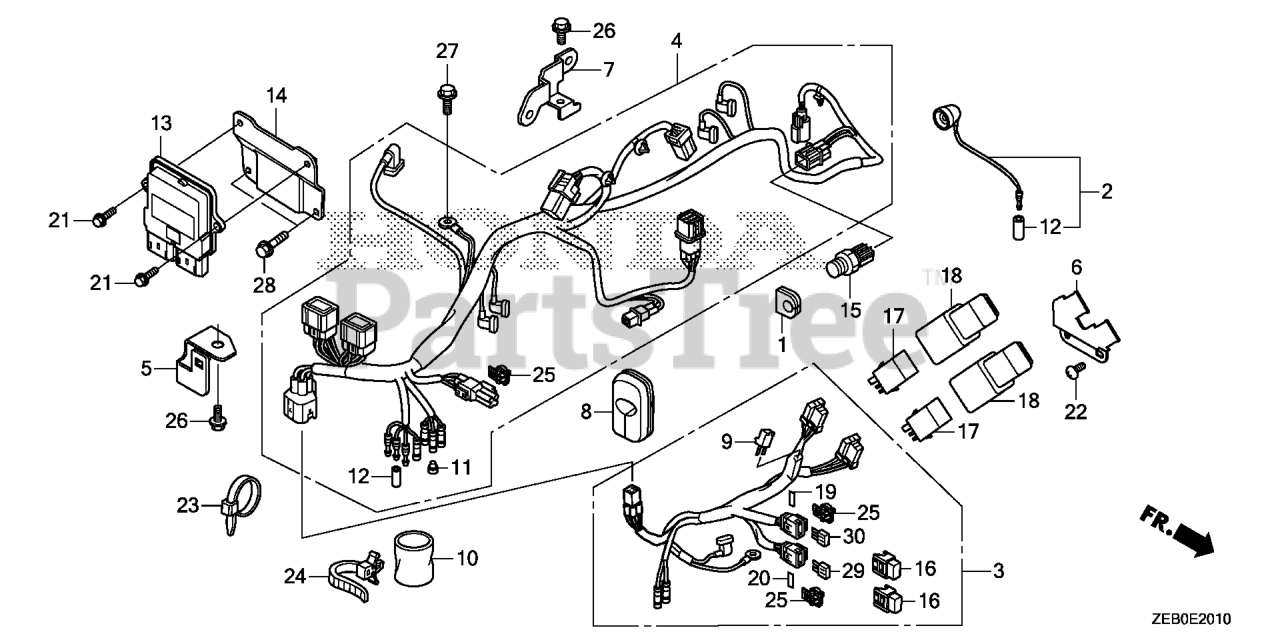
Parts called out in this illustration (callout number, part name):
1	GROMMET, WIRE
2	SUB-WIRE ASSY.
3	SUB-WIRE HARNESS ASSY., ENGINE
4	WIRE HARNESS ASSY., ENGINE
5	BRACKET, HARNESS CLIP
6	BRACKET, RELAY
7	BRACKET B, HARNESS
8	GROMMET, WIRE
9	CONNECTOR, DIODE (2P) (3A)
11	PLUG, CONNECTOR (INNER) (TROLLING CONTROL)
12	PLUG, CONNECTOR (OUTER) (ENGINE NO.)
13	CONTROL UNIT, ELECTRONIC
14	STAY, ELECTRONIC CONTROL UNIT
15	SENSOR ASSY., TEMPERATURE
16	COVER ASSY., FUSE
17	RELAY, POWER (MICRO ISO 4P) (BLUE)
18	SUSPENSION, POWER RELAY
19	LABEL, FUSE (30A)
20	LABEL, FUSE (15A)
21	BOLT, FLANGE (5X14)
22	SCREW, TRUSS (6X12)
23	BAND, WIRE (BLACK)
24	CABLE, STRAP
25	CLIP, CONNECTOR (BLACK)
26	BOLT, FLANGE (6X14)
27	BOLT, FLANGE (6X18)
28	BOLT, FLANGE (6X22)
29	FUSE, MINI (15A)
30	FUSE, MINI (30A)
